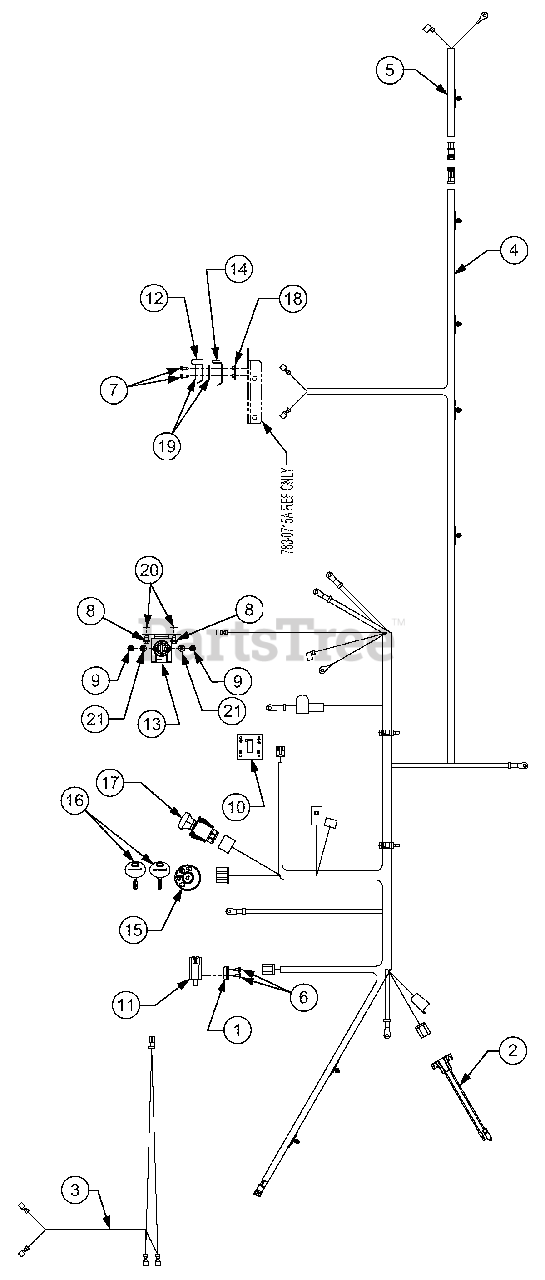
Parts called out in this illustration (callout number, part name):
1	Plate, Switch
2	Harness Assembly, Kawasaki
3	Harness Assembly, Headlight
4	Harness Assembly
5	Harness Assembly, Safety, Reverse
6	Screw, Hx. Wash. Hd. Tapp, 10-16 x .5
7	Screw, Hx. Wash. Hd. Tapp, 8-18 x .5
8	Screw, Hx. Wash. Hd. Tapp, 1/4-20, 0.5
9	Nut, Hex, 1/4-20, Gr5
10	Indicator/ Meter Hour
11	Switch, Interlock
12	Switch, Outer Seat Spring
13	Solenoid, Starter, 12V
14	Switch, Inner Seat Spring
15	Switch, Key, 4-Position
16	Key, Switch, Plastic
17	Switch, Electric PTO, Yellow Knob
18	Plate, Insulator Boss
19	Plate, Insulator
20	Washer, Lock, Ext 1/4
21	Washer, Lock, 1/4
